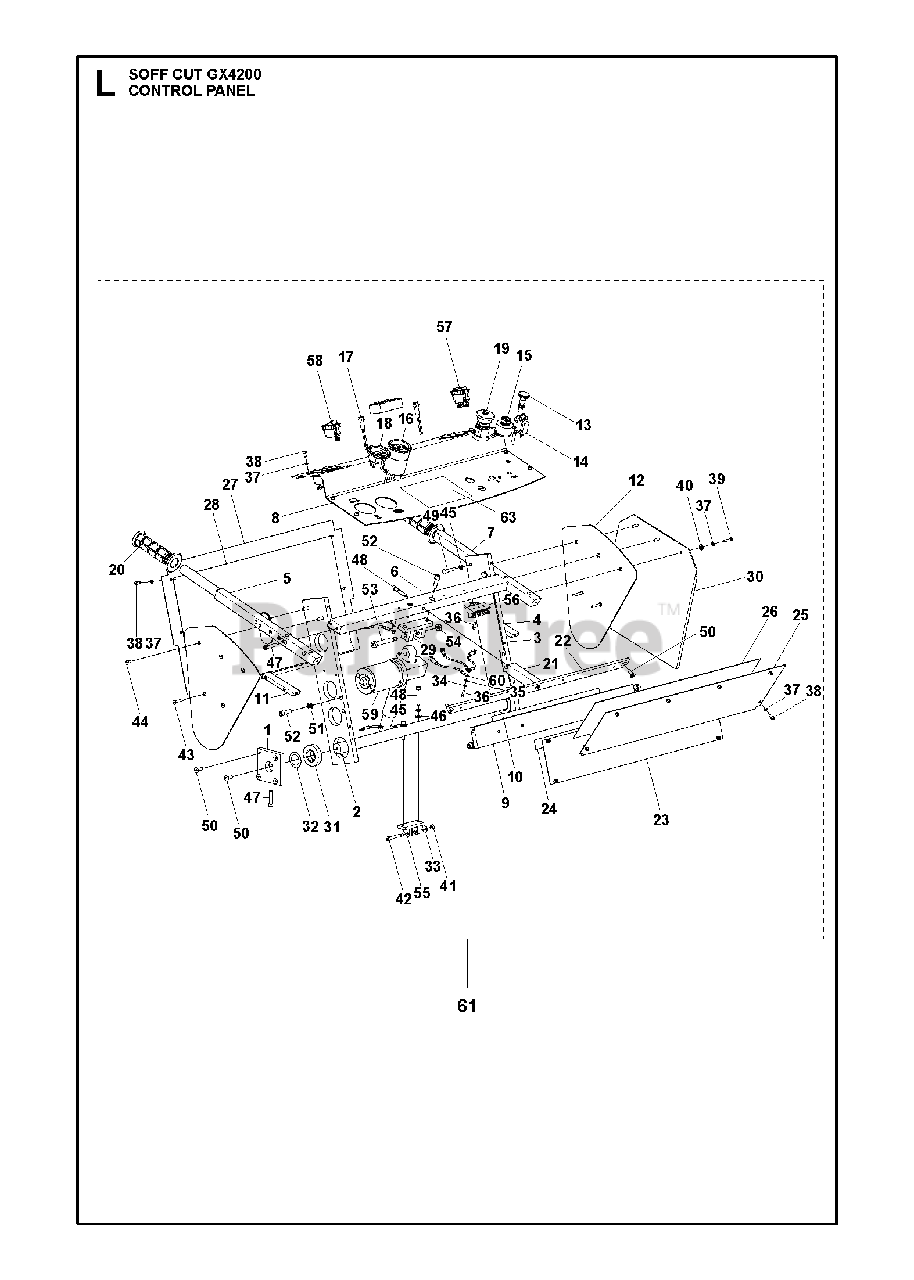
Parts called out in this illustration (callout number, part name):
10	RUBBER FOR 3535-01 14"1/8L 2"W
24	RUBBER FOR 3526 20 7/8L 7/8W
54	NUT
